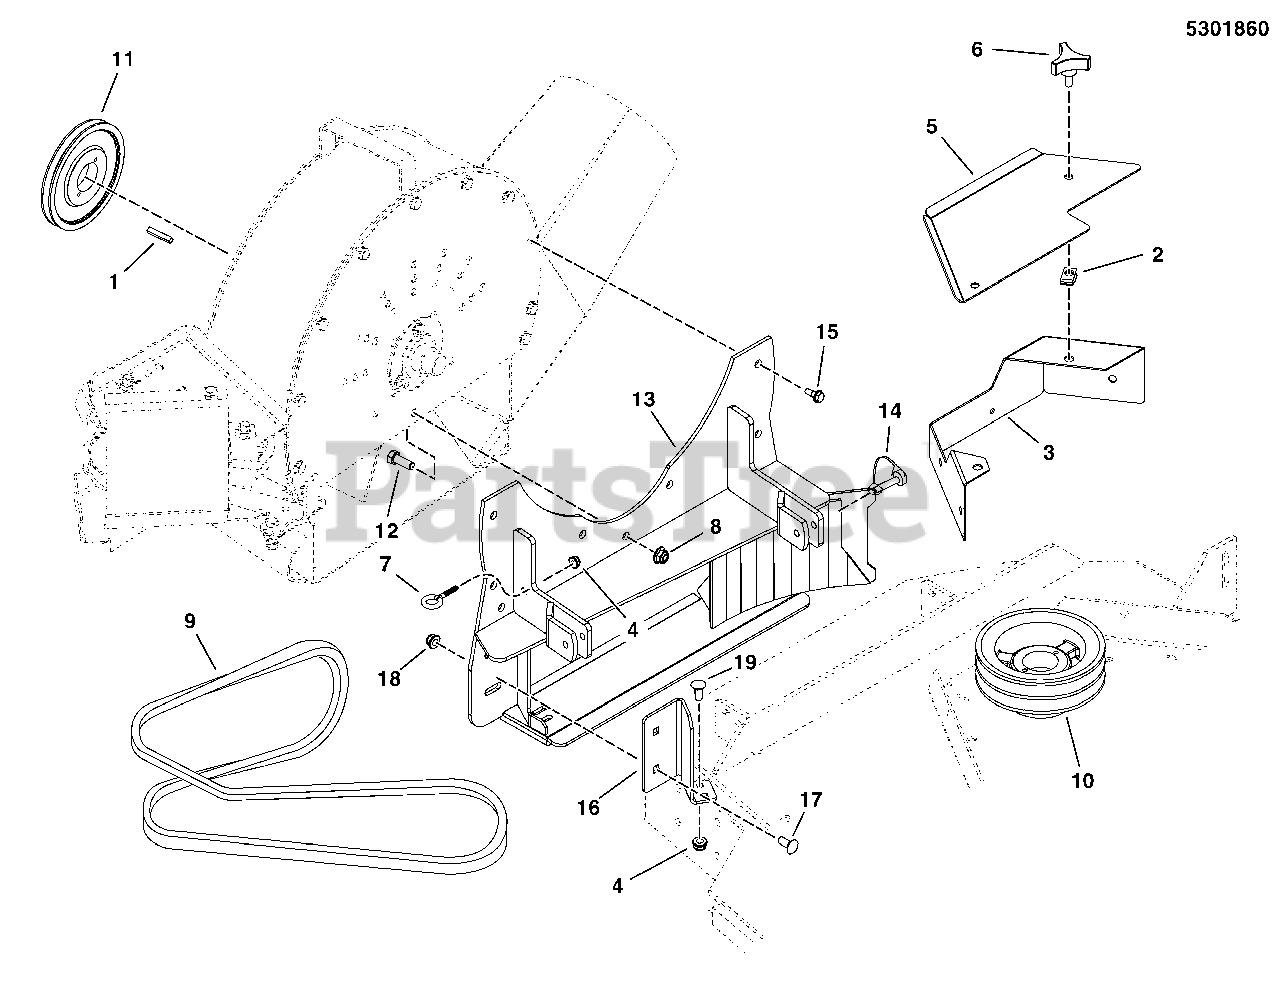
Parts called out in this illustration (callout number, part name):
1	KEY 1/4 SQ X 1 1/2 LONG
2	BODY CLIP, 5/16-18-7GA MATERIAL
3	GUARD, DECK, 61", FASTVAC - BLK
4	NUT, 1/4-20 HEX NYLOCK FLANGE (5025391)
5	GUARD, BELT, 61", FASTVAC - BLK
6	KNOB, PLASTIC, 5/16-18 X 3/4
7	EYEBOLT, 1/4-20 X 2
8	NUT, 3/8-16 HEX NYLOCK FLANGE
9	BELT, 96" EL, A-SECT, ARAMID, WRAPPED
10	PULLEY, DECK,61 BLOWER UNIT
11	PULLEY, BLOWER AXLE, 61
12	BOLT, 3/8-16 X 1 GD5 YZ
13	WELD, BLOWER MOUNT, 61 - BLK
14	SNAPPERPIN, 5/16 X 2
15	BOLT, 5/16-18 X 5/8" Self Lock
16	BRACKET,DEFLECTOR PLATE, 61
17	BOLT, 5/16-18 X 3/4, CARRIAGE
18	NUT, 5/16-18 HEX NYLOCK FLANGE
19	BOLT-RD HD SH SQ NK 1/4-20X0. 625 G5 BLK
